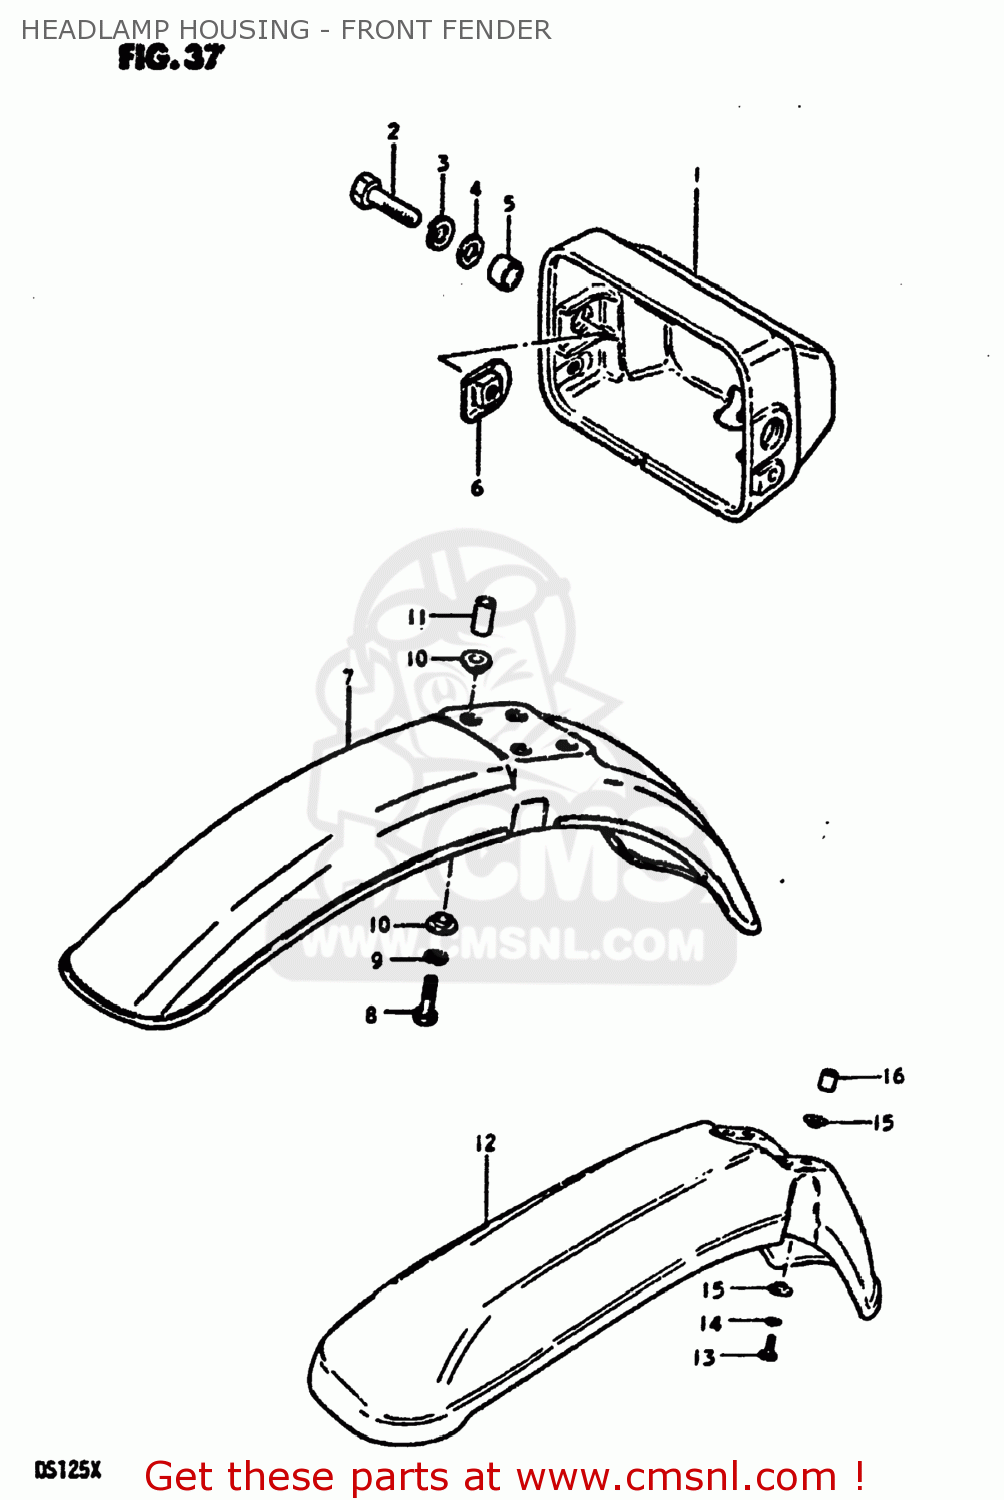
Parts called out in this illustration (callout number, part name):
1	HOUSING,HEADLAMP
2	BOLT
3	LOCK WASHER
4	WASHER
5	SPACER (8.8X12X7)
6	PLATE,HEADLAMP HOUSING
7	FENDER,FRONT
8	BOLT 6X40
9	LOCK WASHER
10	SPACER
11	SPACER (6.8X10X20)
12	FENDER,FRONT
13	BOLT
14	LOCK WASHER
15	SPACER
16	SPACER
